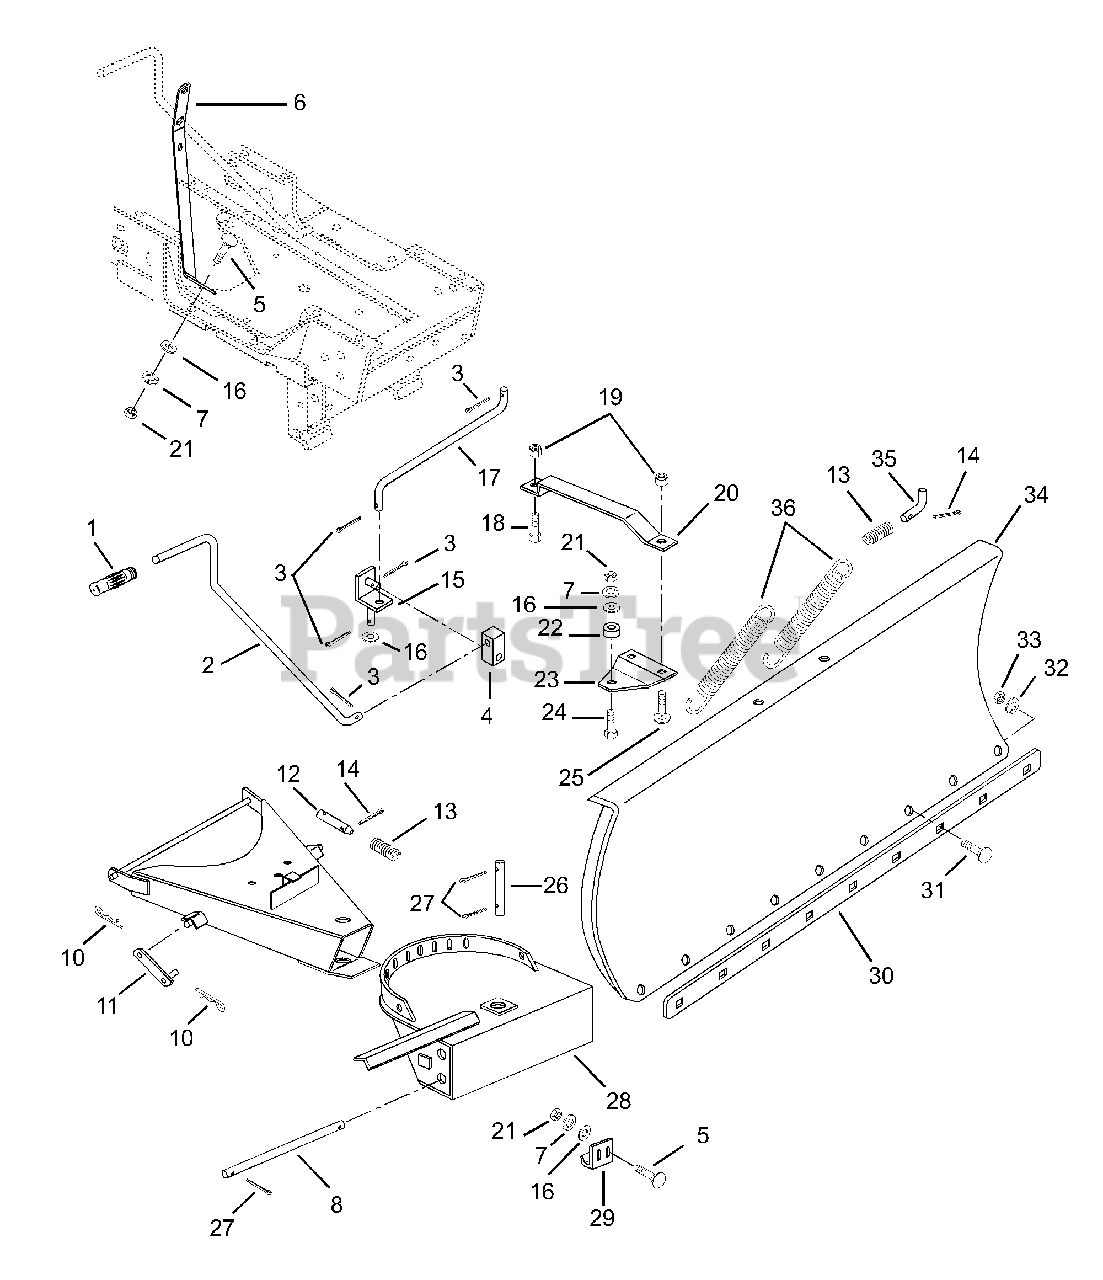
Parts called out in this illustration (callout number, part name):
1	GRIP - 3/8 ID X 2 7/8 - BLACK
3	@PIN-CTR .12X.75 EXTPRSQCT YWZ
4	UNIVERSAL BLOCK JOINT
5	@BLT-RDHDSQNK .38-16X1.00 G2YZ
6	SUPPORT, ROD
7	@WSHR-LK .38X.094 REG YWZC
9	54 IN FRAME
10	PIN-HAIR INT .14X.4X2.75
11	ARM, LIFT LINK
12	LATCH PIN
13	SG-COMP .080X.85X1.44
14	@PIN-CTR .12X1.00 EXTPRSQCT YZ
16	@WSHR-FL-STL.438X1.00X.083 YWZ
18	@BLT-HEX .31-18X1.25 GR5 YWZC
19	@NUT-LK-CTR .31-18 YWZC
21	@NUT-HEX .38-16 YWZC
22	SPACER .406X.749X.162
23	PIVOT PLATE
24	@BLT-HEX .38-16X1.00 GR5 YWZC
25	BLT-RDHDSQSHK.31-18X.75 GR2 YW
27	@PIN-CTR .18X1.00 EXTPRSQCT YZ
28	SUPPORT
29	SKID SHOE
30	WEAR PLATE
31	@BLT-RDHDSQNK .31-18X1.00 G5YZ
32	@WSHR-LK .31X.078 REG YWZC
33	@NUT-HEX .31-18 YWZC
34	54 IN BLADE
35	JACK PIN
36	SG-TENS .187X1.50X9.94 WLD 40
